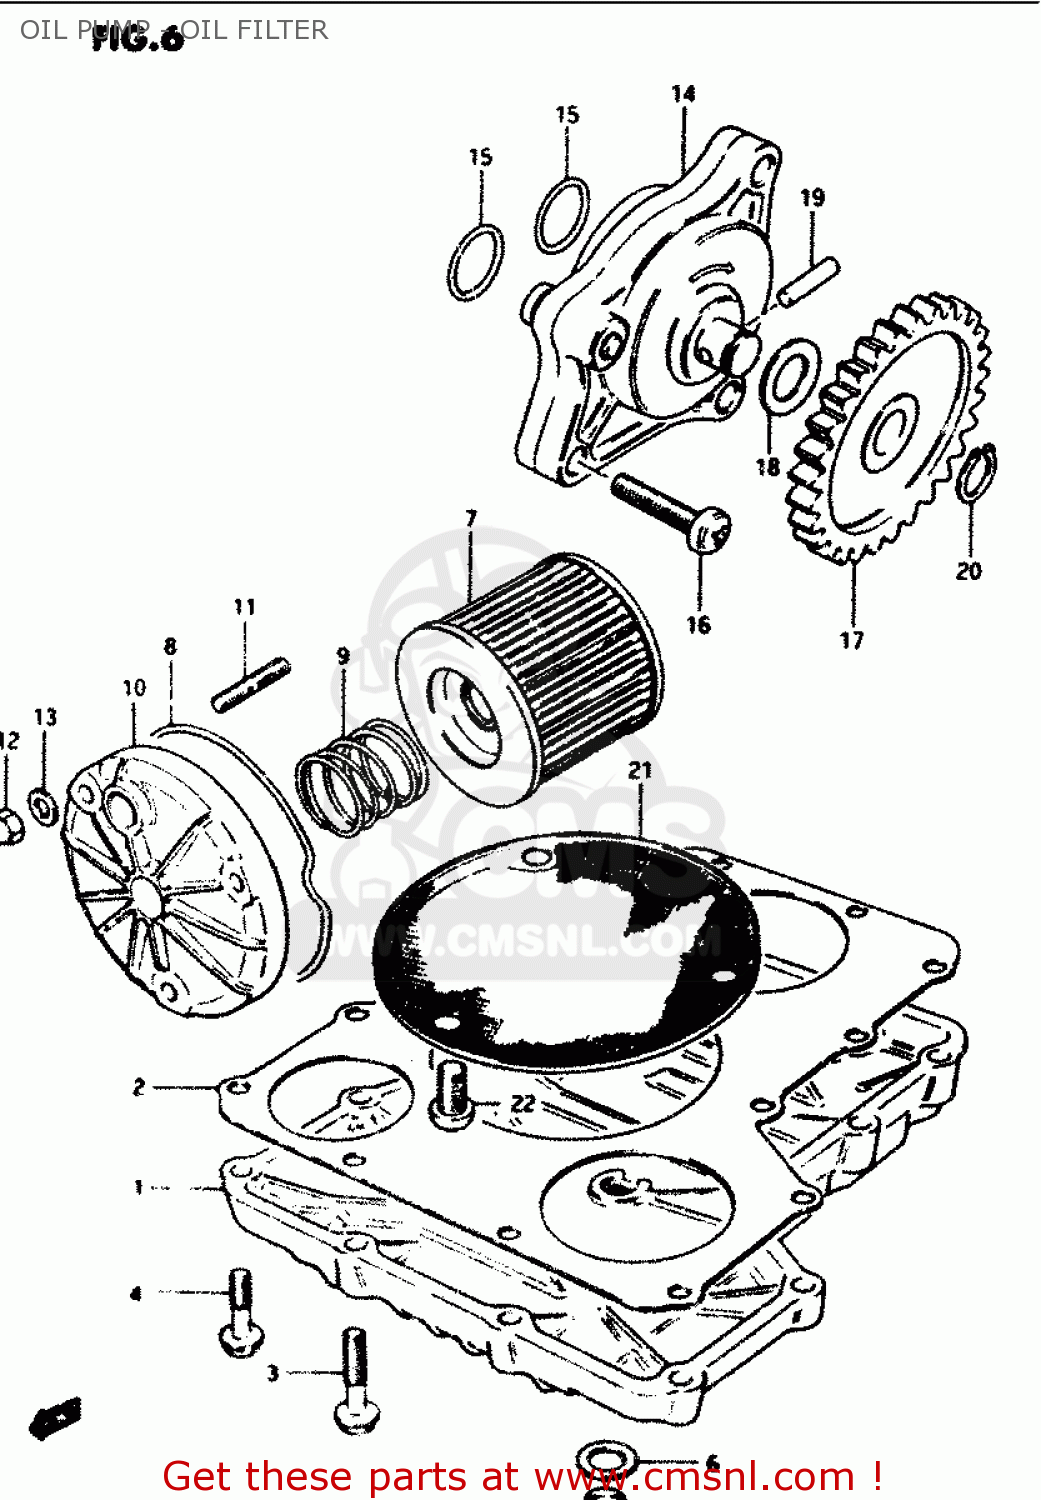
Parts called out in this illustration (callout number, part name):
1	PAN,OIL
2	GASKET,OIL PAN (MCA)
3	BOLT 6X30
4	BOLT
5	PLUG
6	GASKET(14X19.2X2) (NAS)
7	FILTER ASSY,ENGINE OIL
8	O RING,OIL FILTER CHAMBER CAP
9	SPRING
10	CAP,OIL FILTER
11	STUD 6X20
12	NUT 6MM
13	WASHER
14	PUMP ASSEMBLY,ENGINE OIL
15	O RING(D:1.9,ID:13)
16	SCREW
17	GEAR,ENG OIL PUMP DRIVEN(NT:33
18	SHIM
19	PIN(4X15.8)
20	CIRCLIP
21	STRAINER,ENGINE OIL
22	SCREW 6X12
